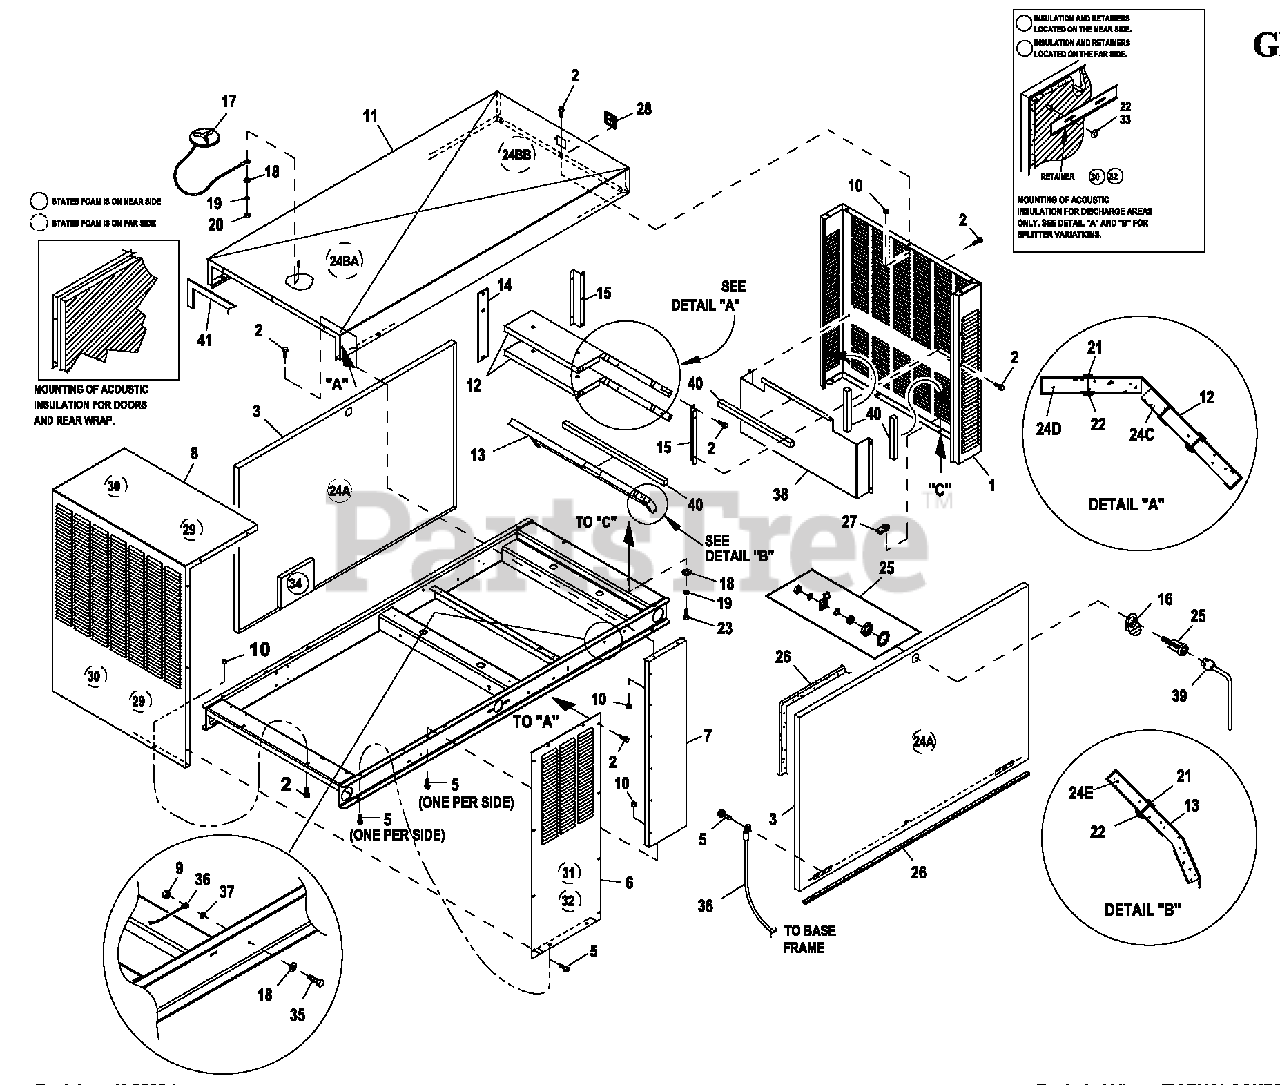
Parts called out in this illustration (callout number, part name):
1	PANEL TOP QTA C2
2	ACCESS COVER 160 X 170 GALV
3	PANEL SIDES FRONT QTA C2
4	PANEL REAR SIDES QTA C2
5	PANEL TOP MOUNT QTA C2
6	PANEL LOW ER FRONT QTA C2
7	GUARD-ALT REAR
8	BUSHING SNAP SB-2.5-31
9	NUT HEX M14-2.0 G8 YELCHR
10	SCREW THF M6-1 X 16 N WA Z/JS
11	WIRETUNNEL-ALT
